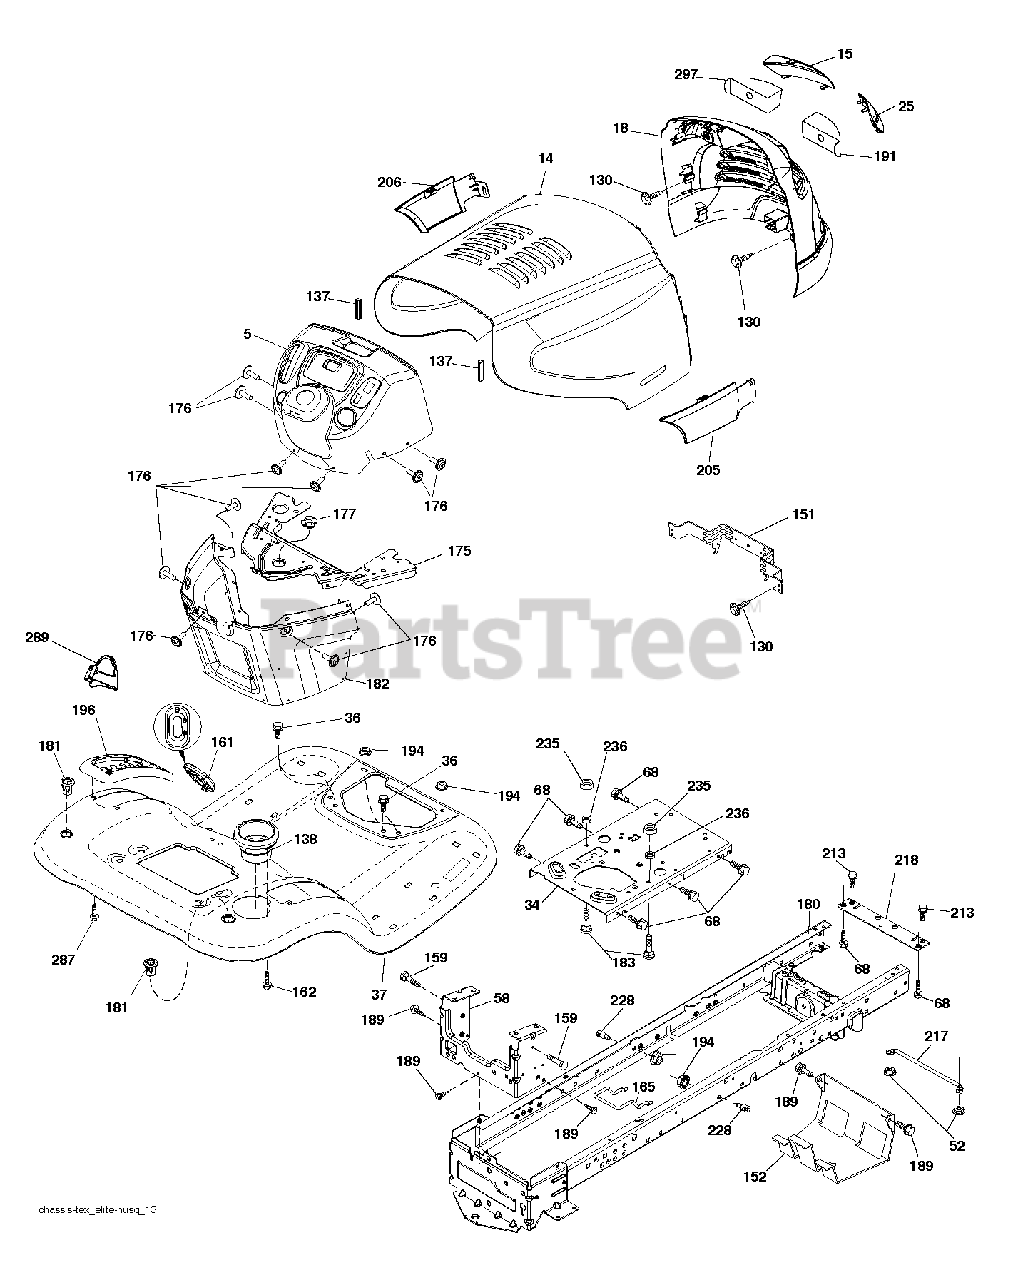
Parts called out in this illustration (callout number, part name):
5	DASH UPPER
14	HOOD.ELT.HUS/BSC.S/TP.SKT.421
18	GRILLE.ELITE HUSQ.BLACK.DL.
36	SCREW 5/16"
37	FENDER.TLT.FS.W/CPH/FW/RSF.428
52	LOCKNUT
58	DRAWBAR UPPER 2PC SMALL FENDER
68	SCREW LT
130	SCREW.#10 X 0.750.BOS (2 2)
137	BUMPER.HOOD.LARGE.1.75"
138	CUPHOLDER.TL.TEX.BLACK
151	BRACKET PIVOT
152	SHIELD.BROWNING.W/TEX
159	SCREW, 3/8-16X3/4
161	WINDOW.FUEL.LT.TEX.BLACK
162	SCREW.HI-LO.CONSOLE
165	SUPPORT.TANK.REAR.W/TEX
175	CROSSMEMBER.LT
176	SCREW.#10-24X5/8.RN.QU
177	BUSHING,STEERING
180	CHASS.WLDMNT.TL.12GA/2P.48/54
181	FEND/FTRST.PCH.CPH.NFW
182	DASH.LOWER.LT.CCS
183	BOLT.5/16-18X1-1/4 FULL THD
189	SCREW
191	INSERT LENS
194	NUT LOCK HEX FLANGE 5/16-18
196	CONSOLE.ASM.DECKLFT.BL/RBT.TLT
205	SKIRT.SIDE.RH.ELITE.HUSQ.428
206	SKIRT.SIDE.LH.ELITE.HUSQ.BLACK
213	BOLT
217	ROD.PIVOT.HOOD
218	X-PIECE.HOOD.STOP.NON/
228	STUD.FASTNER.W/ANTI-ROTATE
235	SPACER FENDER
236	NUT.CENTERLOCK.5/16-
287	SCREW 1/4X20
289	PLUG CRUISE HOOK PHONE
297	INSERT.REFLECTIVE.RH.
